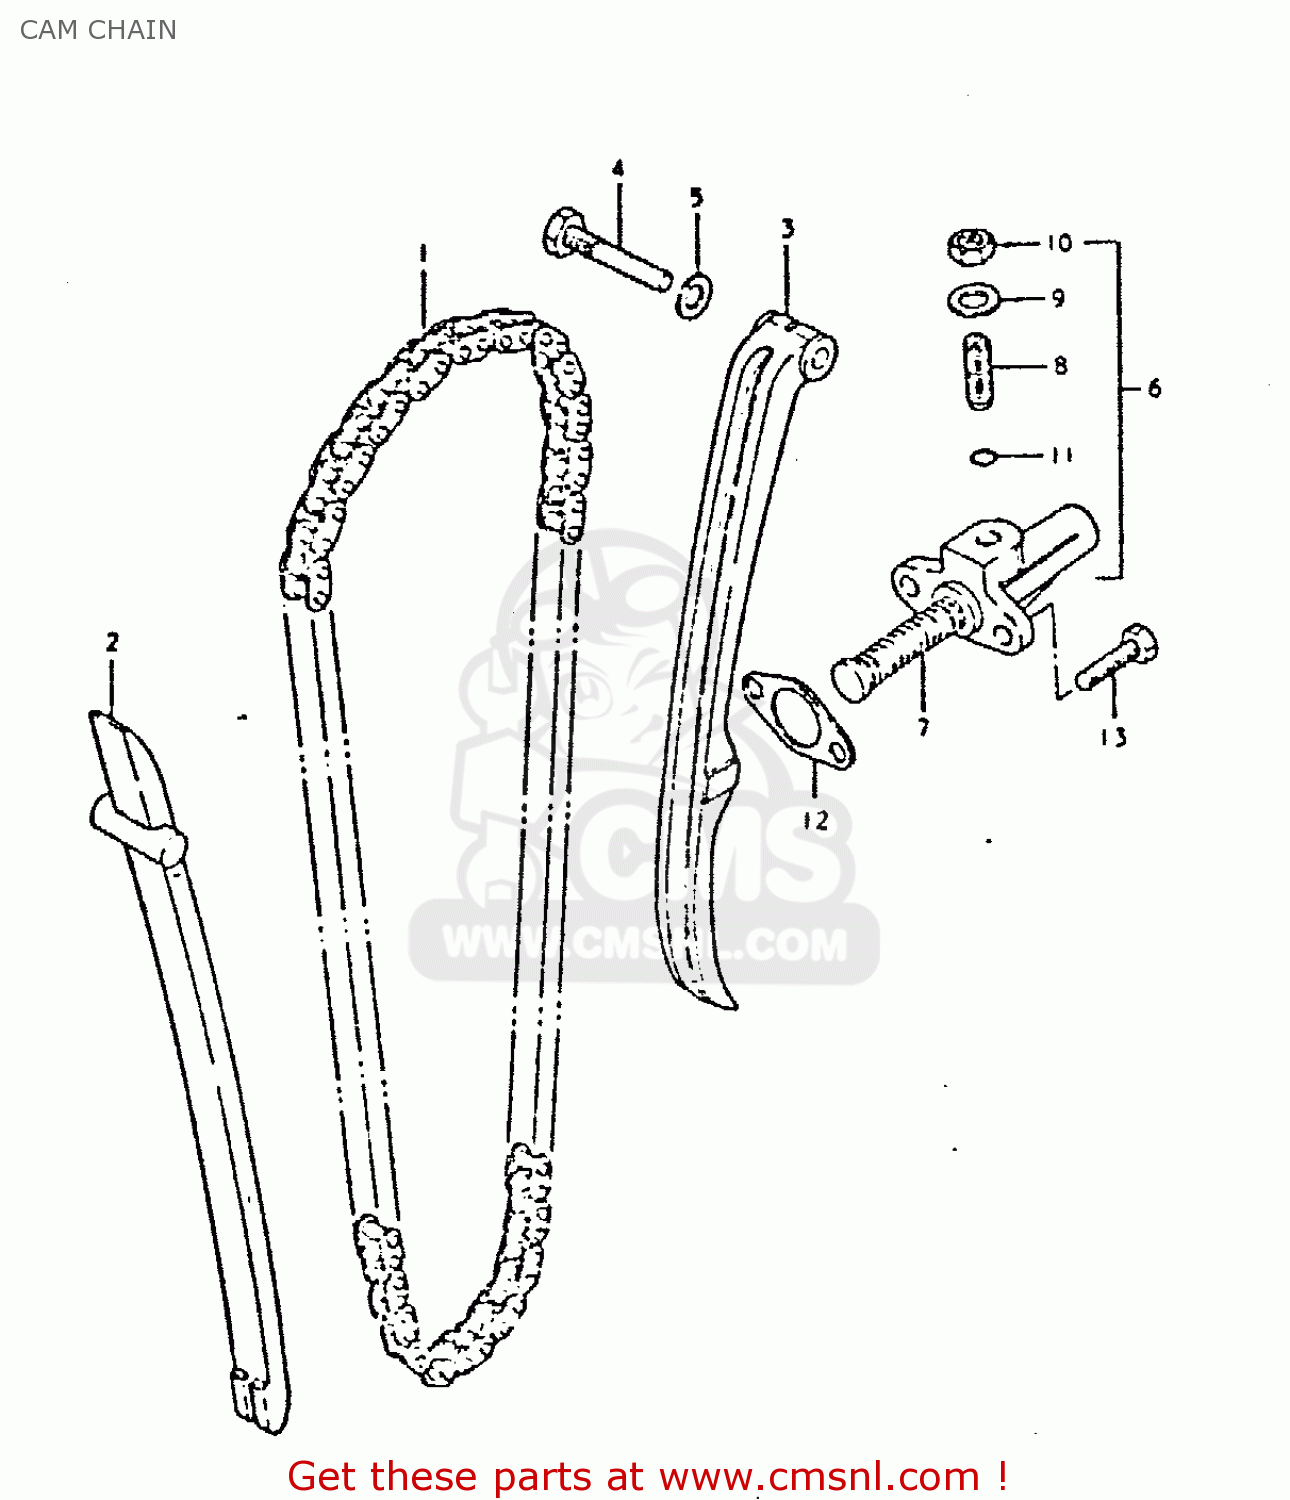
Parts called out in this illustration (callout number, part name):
1	CHAIN,CAMSHAFT DRIVE
2	GUIDE,CAM CHAIN
3	TENSIONER,CAM CHAIN
4	BOLT,CAM CHAIN TENSIONER
5	GASKET 8.2X14X1 (NAS)
6	ADJUSTER ASSEMBLY,TENSIONER
7	SPRING
8	SCREW
9	WASHER
10	NUT
11	O-RING
12	GASKET,TENSIONER ADJUSTER (NAS)
13	BOLT
